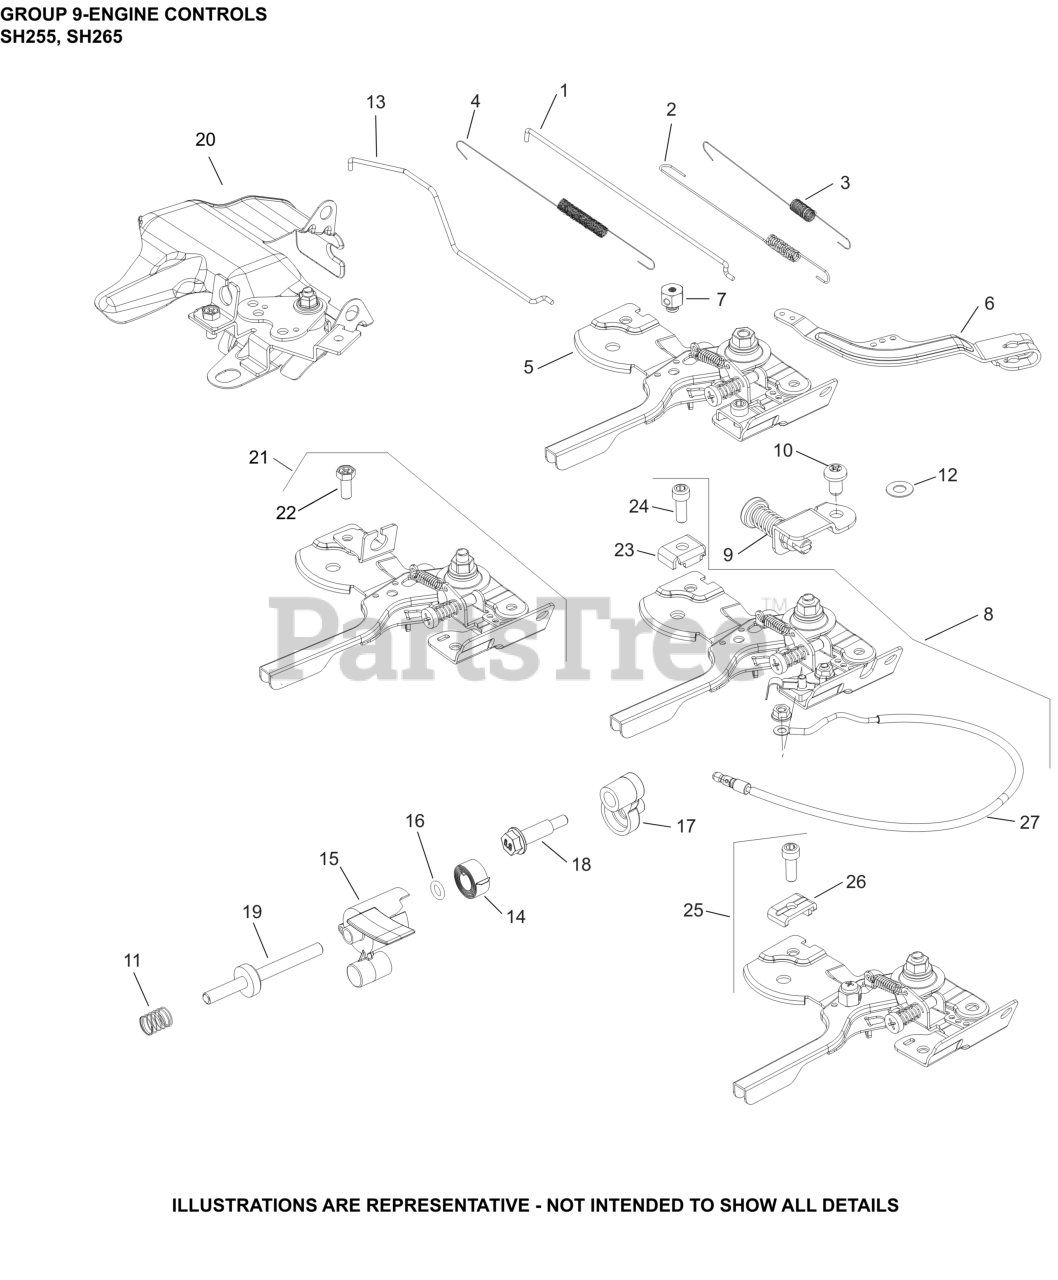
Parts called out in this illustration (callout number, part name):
1	LINKAGE, GOVERNOR-USE 18 079 05-S
2	SPRING, GOVERNOR
4	SPRING, LINKAGE
5	VARIABLE SPD CNTRL ASSY W/O KILL
6	KIT, GOVERNOR LEVER
NI	CLAMP, CABLE
